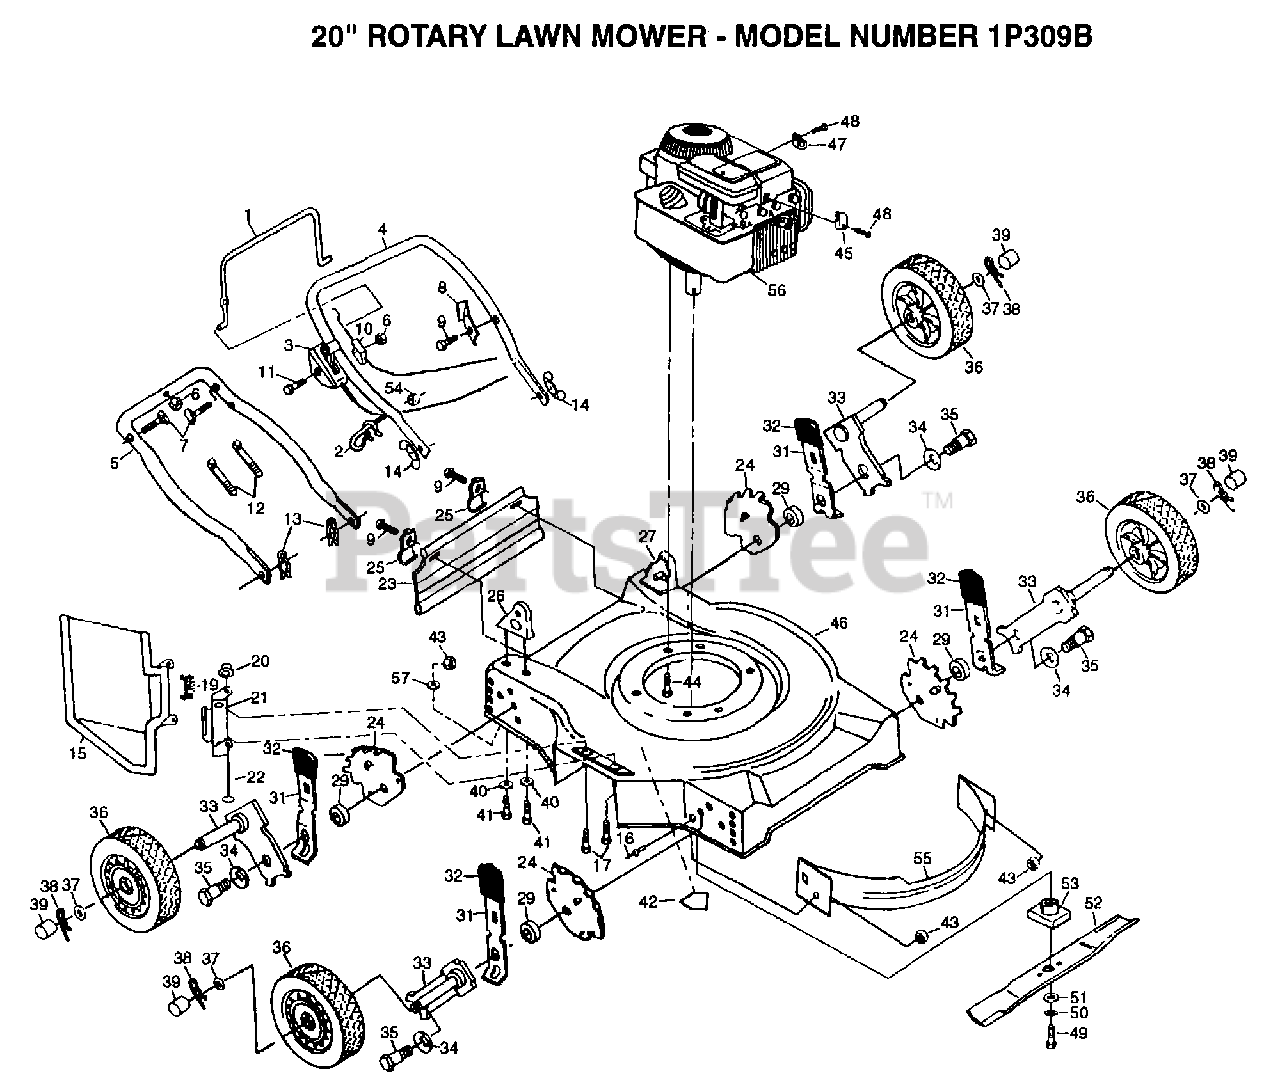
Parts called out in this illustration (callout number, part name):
1	CONTROL BAR PM
2	ROPE GUIDE
3	CONTROL THROTTLE
7	BOLT.HANDLE.LM
8	"BRKT,UPSTOP"
9	TAPPING SCREW
10	"CABLE,ENG ZONE CO"
11	SCREW.HXHD.WASH.
13	HAIRPIN COTTER
14	"NUT,WING PM"
15	"GRD,DISCHARGE"
16	BLIND RIVET
17	SCREW
19	"SPRING,TORSION"
20	PUSH ON SPEED NUT
21	"BRKT,HSG "
23	SKIRT.RD.20/22
24	BRACKET.ADJ.9POS.
25	"BRKT,DEFL PM"
31	SPRING SELECTOR
32	KNOB PM
33	AXLE ARM
34	"WASHER, BELLEVIL."
35	BOLT SHLD 3/8-16
36	WHEEL&TIRE
37	WASHER
38	RETAINER CLIP PM
39	HUB CAP-PLASTIC
40	STEEL WASHER
41	SCREW
42	DECAL HYT
43	LOCKNUT PM
44	SCREW
45	CABLE CLAMP
46	"KIT.HSG.20""SDPUSH"
47	GUIDE CLIP PM
48	SCREW PM
49	SCREW
50	LOCKWASHER
51	"WASHER,HARDEN"
52	BLADE.20.MULCH.AY
53	BLADE ADAPTOR
54	NUT
